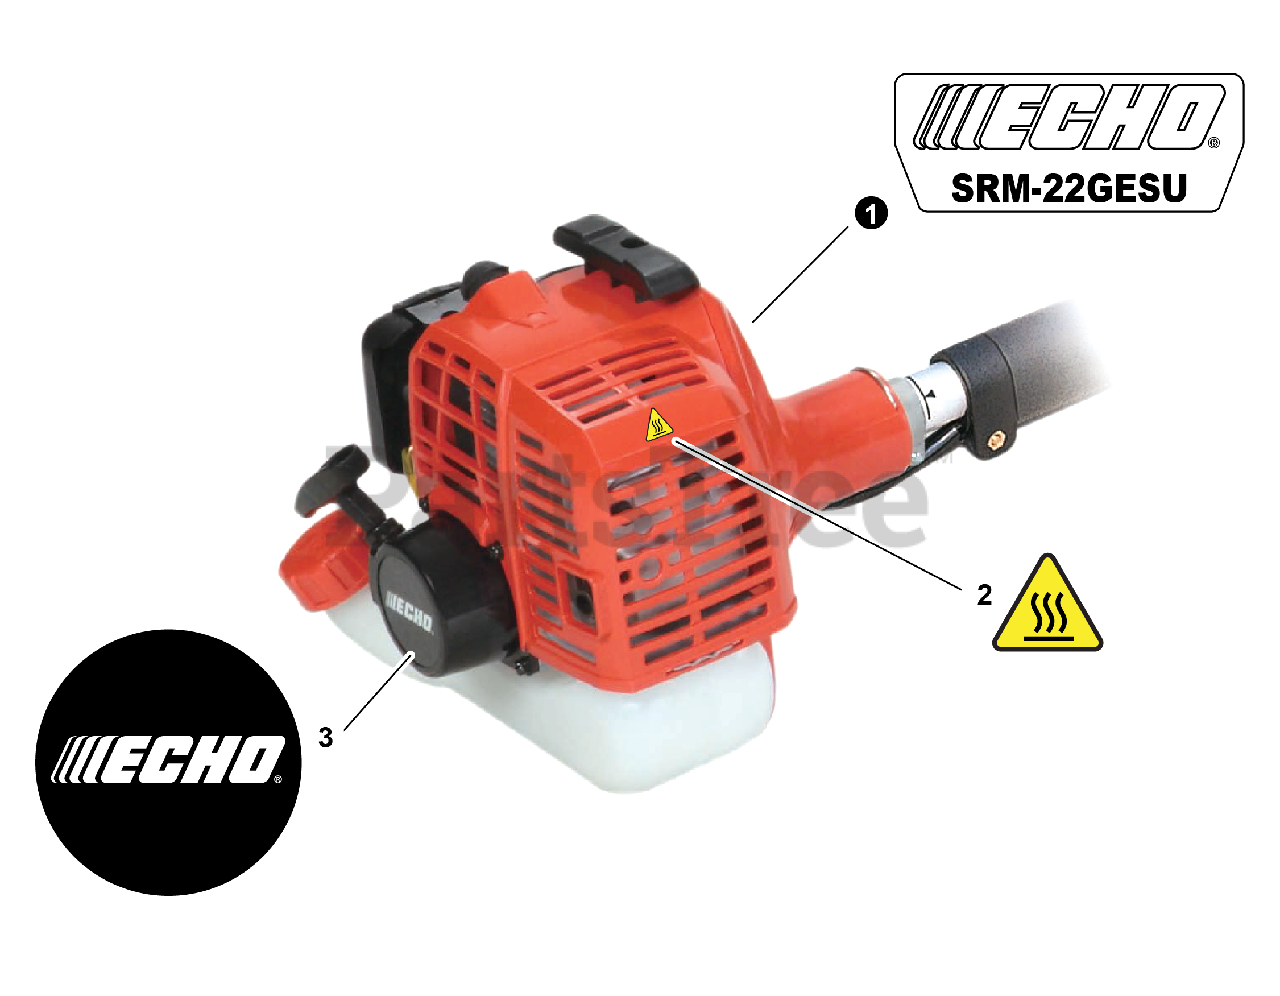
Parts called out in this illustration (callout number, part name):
1	LABEL, MODEL SRM-22GESU
2	LABEL, CAUTION - HOT
3	LABEL, RECOIL STARTER
